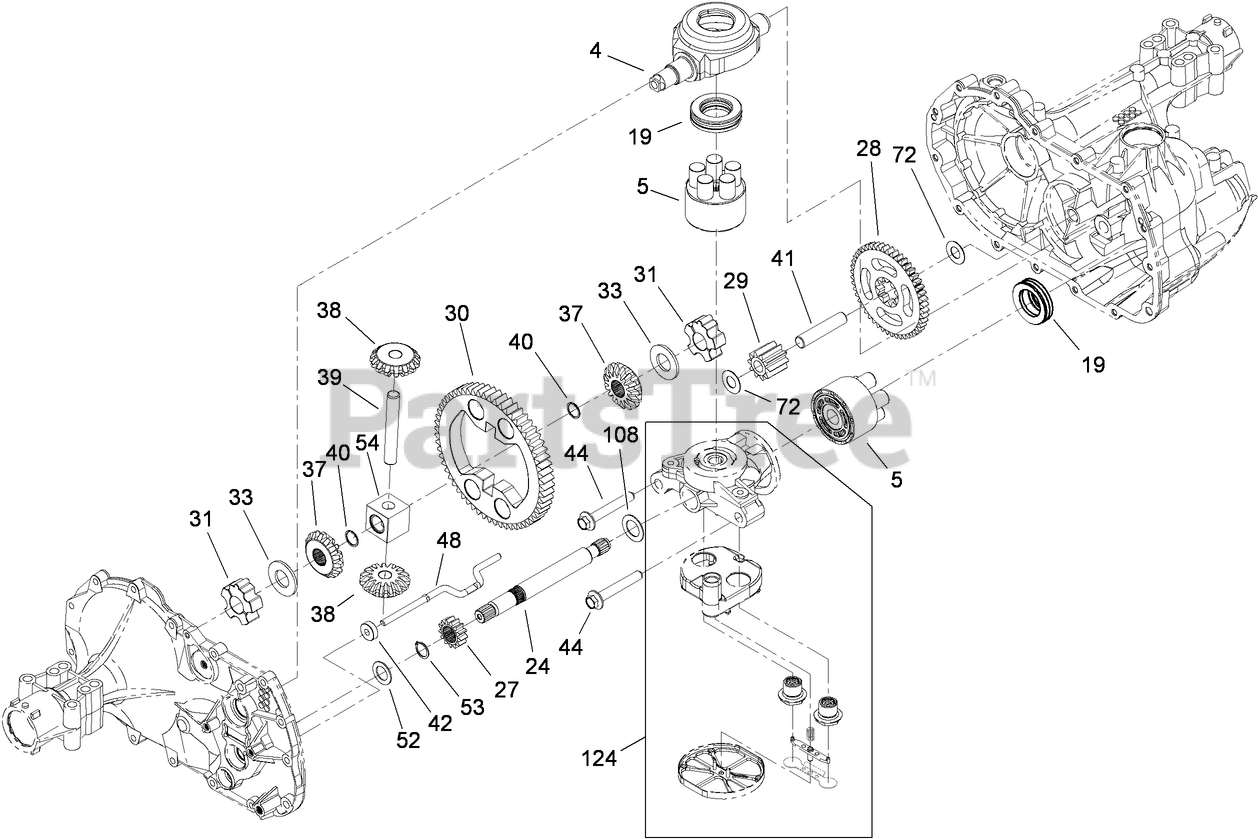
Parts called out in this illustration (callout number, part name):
4	SWASHPLATE-TRUNNION
5	CYLINDER BLOCK KIT
19	BEARING-THRUST
24	SHAFT-MOTOR
27	GEAR-PINNION, 13T
28	GEAR-10T/48T
29	GEAR-JACKSHAFT, 10T
30	GEAR-BULL 60T
31	BEARING-SLEEVE
33	WASHER
37	GEAR-MITER
38	GEAR-MITER 15T
40	RING-RETAINING, SPIRAL
41	PIN-JACKSHAFT
42	MAGNET-RING
48	ROD-ACTUATOR, BYPASS
52	WASHER-FLAT
53	RING-RETAINING
54	BEARING-BLOCK, CENTER
72	WASHER
108	WASHER
124	CENTER SECTION FILTER BYPASS ASM
